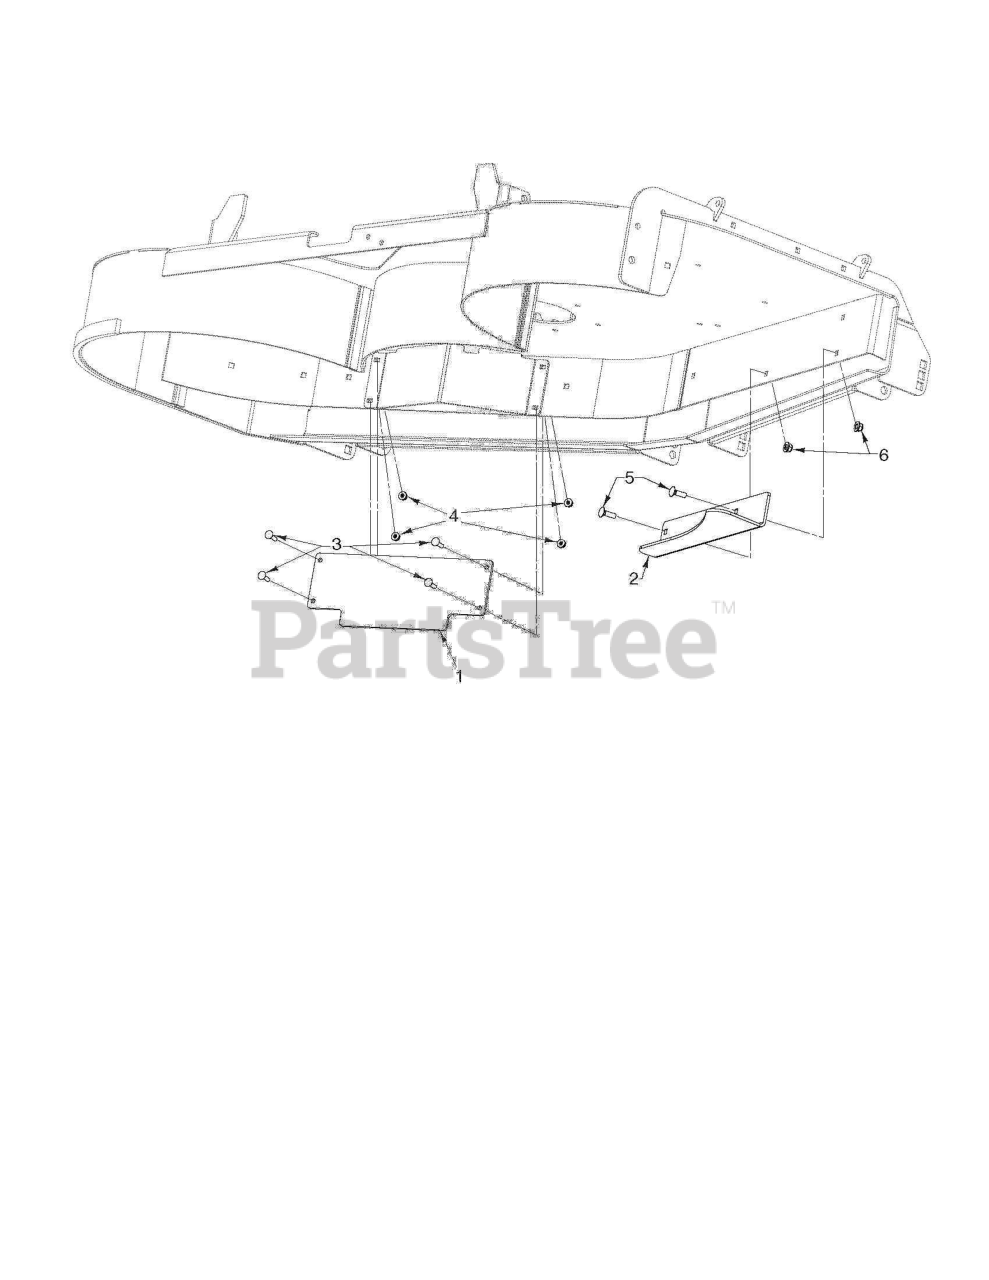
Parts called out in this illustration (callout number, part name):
1	BAFFLE, LH, BLACK
2	BAFFLE, RH, BLACK
3	BOLT CUP HEAD SQUARE NECK 1/4-
4	NUT FLG, NYLOCK, 1/4-20 GR G C
5	Bolts
6	NUT HEXAGON FLANGE 5/16-18 ST
